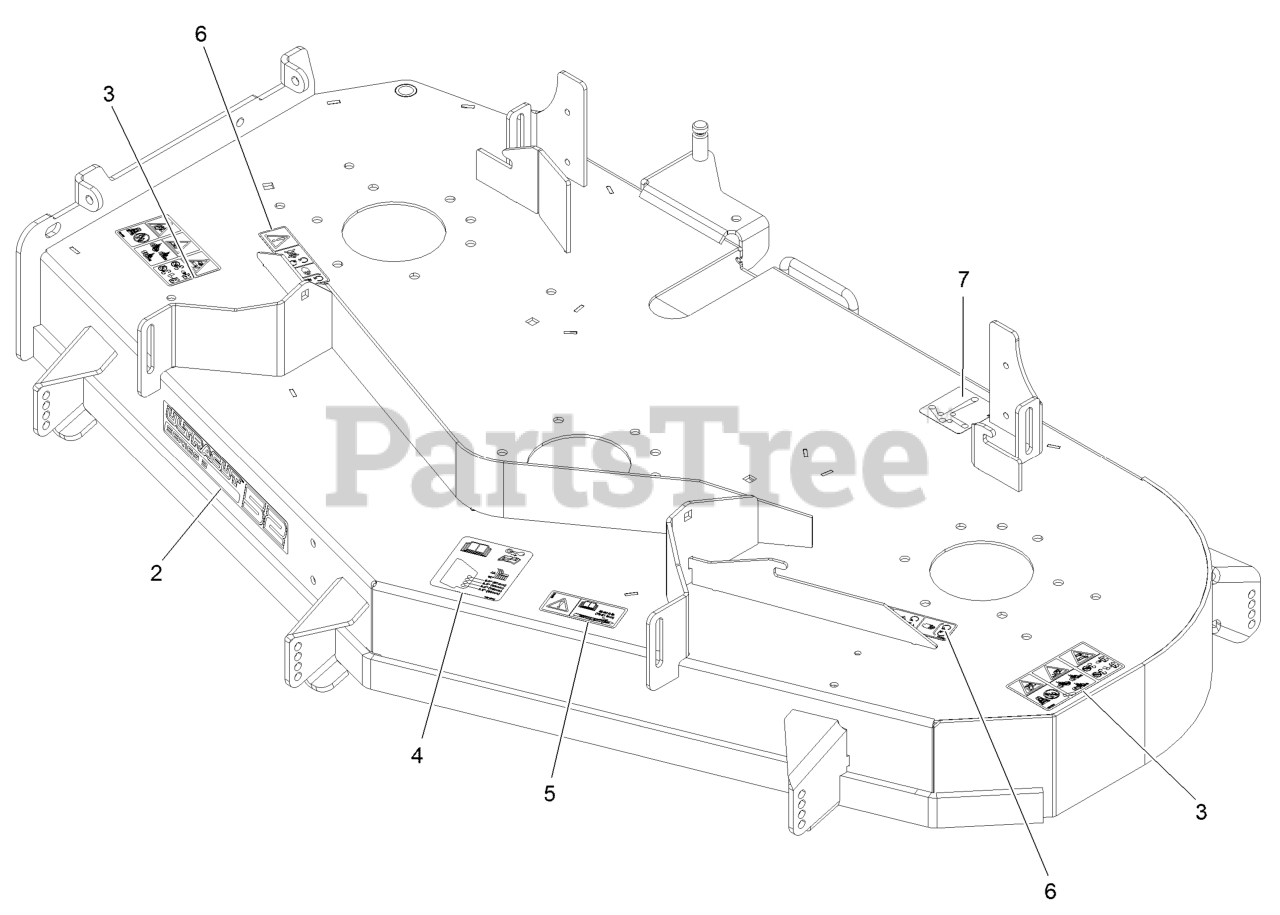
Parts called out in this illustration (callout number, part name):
2	Decal-Ultracut 52 Series 3
3	Decal-Danger Thrown Objects
4	Decal-Roller, Anti-Scalp
5	Decal-Bolt Torque
6	Decal-Missing, Cover
7	Decal-Belt Routing
